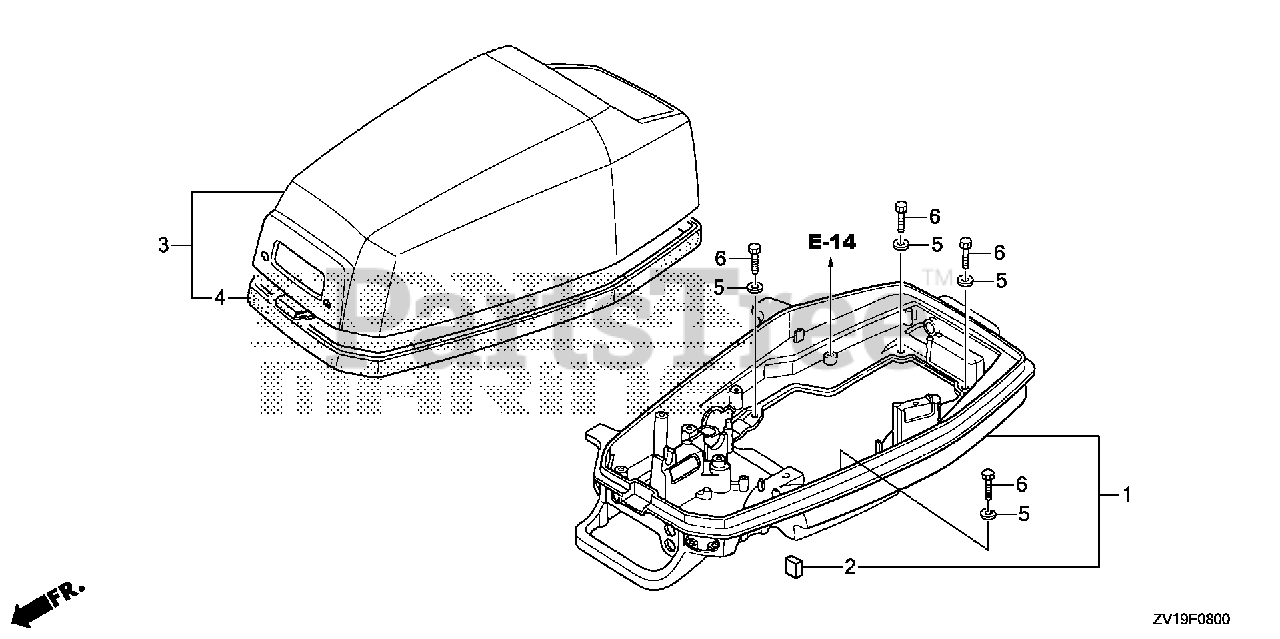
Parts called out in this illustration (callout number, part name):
1	CASE, ENGINE (LOWER) *NHB14M* (AQUA MARINE SILVER METALLIC)
2	RUBBER, DAMPER
3	COVER, ENGINE *NHB14M* (AQUA MARINE SILVER METALLIC)
4	SEAL, ENGINE COVER
5	WASHER, PLAIN (6MM) Use up to Frame SN 4800342.
6	BOLT, HEX. (6X16)
